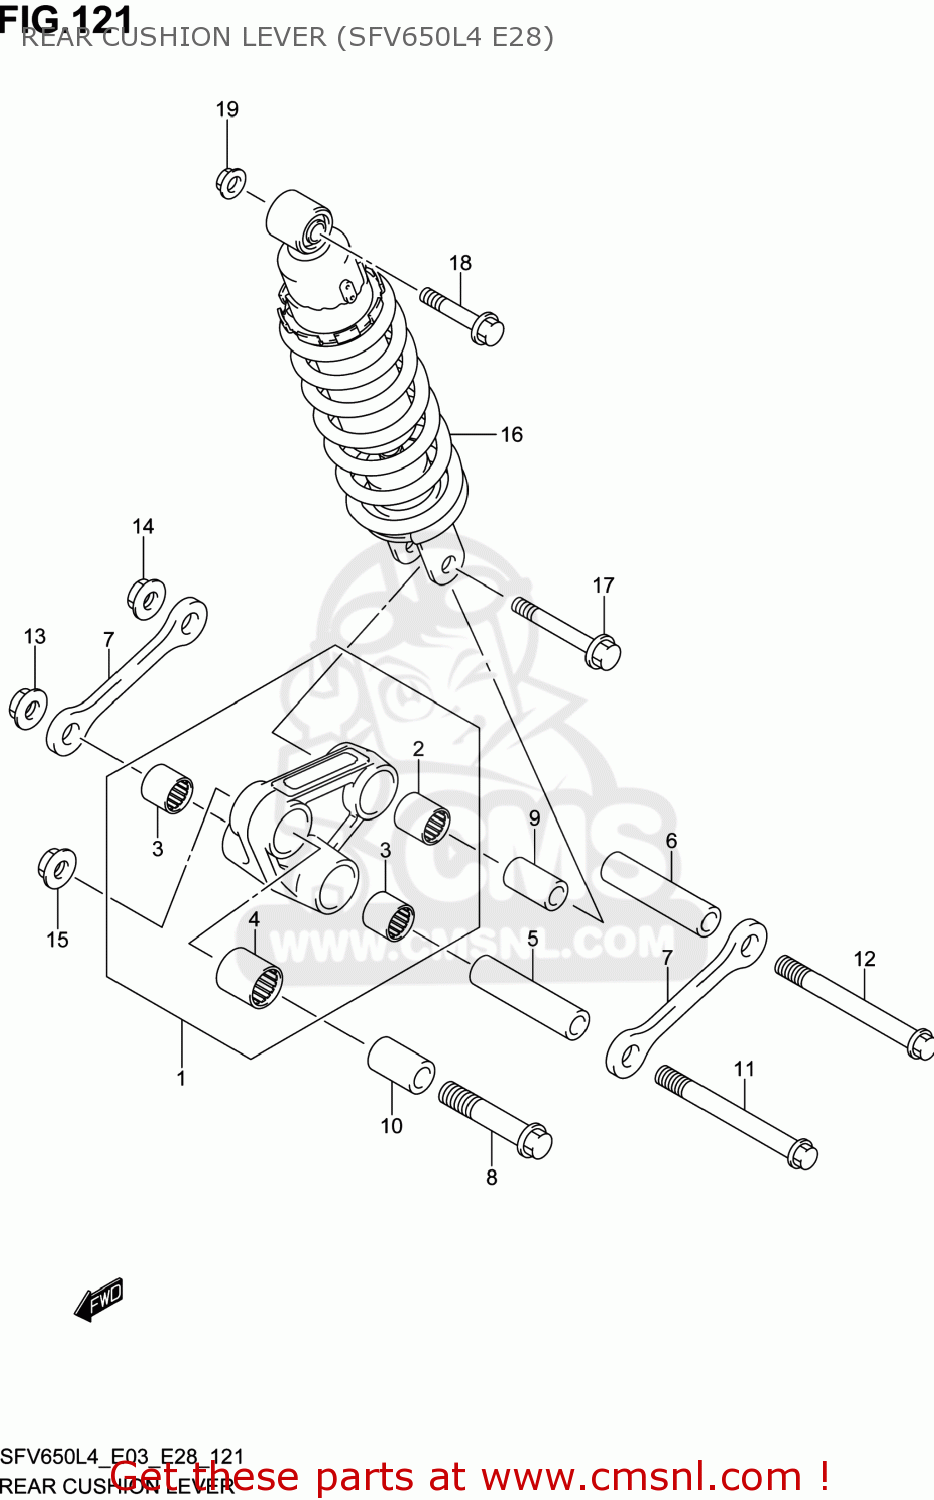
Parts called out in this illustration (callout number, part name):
1	LEVER SET,RR CUSHION
2	BEARING(17X24X26)
3	BEARING(17X24X25)
4	BEARING(20X27X30)
5	SPACER,RR CUSHION LEVER CTR
6	SPACER,RR CUSHION LEVER CTR
7	ROD,RR CUSHION LEVER
8	BOLT,CUSHION LEVER FR
9	SPACER,RR CUSHION LEVER
10	SPACER,RR CUSHION LEVER FR
11	BOLT(12X96)
12	BOLT(12X96)
13	NUT
14	NUT
15	NUT
16	ABSORBER ASSY,RR SHOCK
17	BOLT(10X48)
18	BOLT(10X52)
19	NUT
